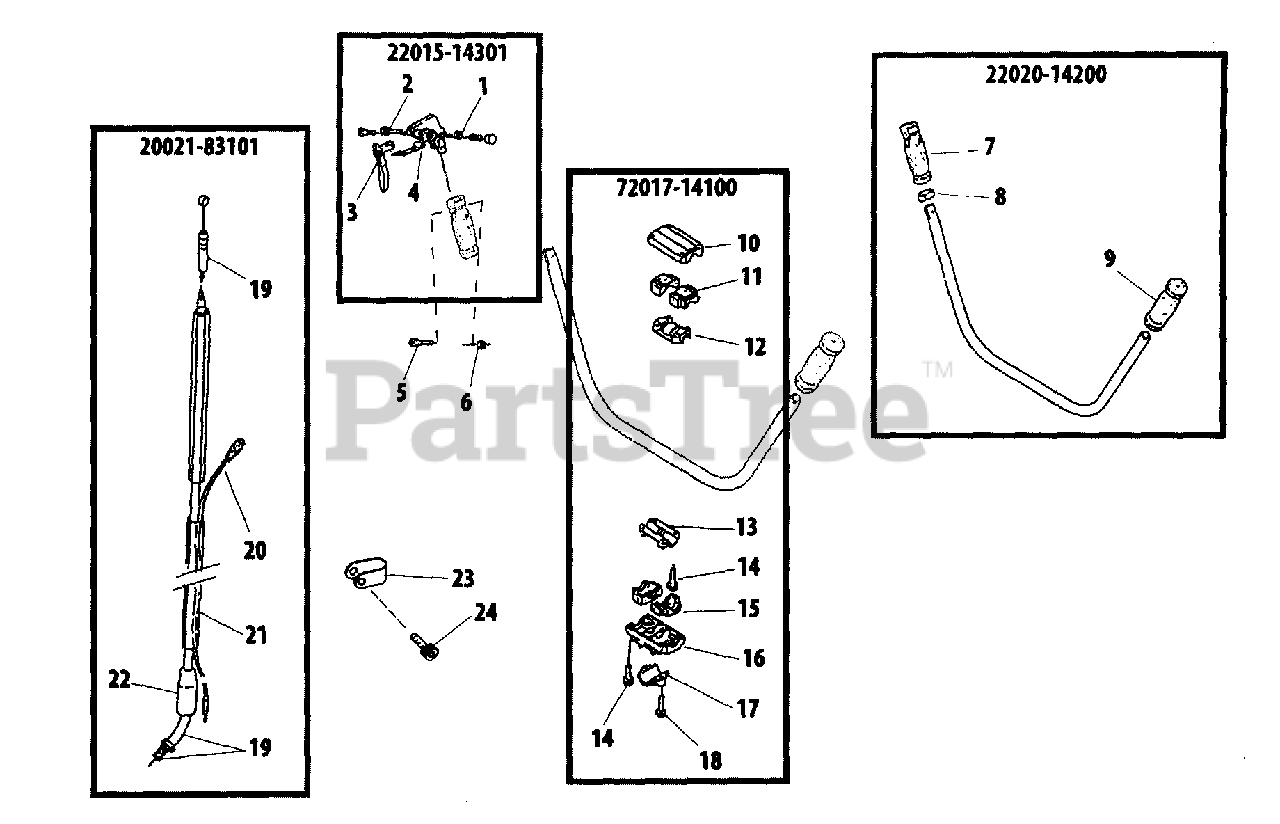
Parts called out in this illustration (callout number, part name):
1	LOCKNUT - 5
2	BOLT
3	TRIGGER, THROTTLE
4	THROTTLE LEVER STOPPER
5	SCREW - 4X24
6	NUT - 4 -- NYLON
7	GRIP - RIGHT
8	HOLDER, CABLE
9	GRIP - LEFT
10	CAP - UPPER
11	CUSHION - UPPER
12	CLAMP - UPPER
13	CLAMP - LOWER
14	SCREW - 5X25
15	CUSHION - LOWER
16	BRACKET, HANDLE
17	SPACER
18	SCREW - 6X25
19	CABLE, THROTTLE
20	WIRE
21	TUBE, PROTECTIVE
22	CAP, DUST
23	CLAMP, CABLE
24	SCREW - 4X12
20021-83101	THROTTLE CONTROL ASSY
22015-14301	THROTTLE CONTROL ASSY
22020-14200	HANDLE ASSY
72017-14100	HANDLE BRACKET KIT
